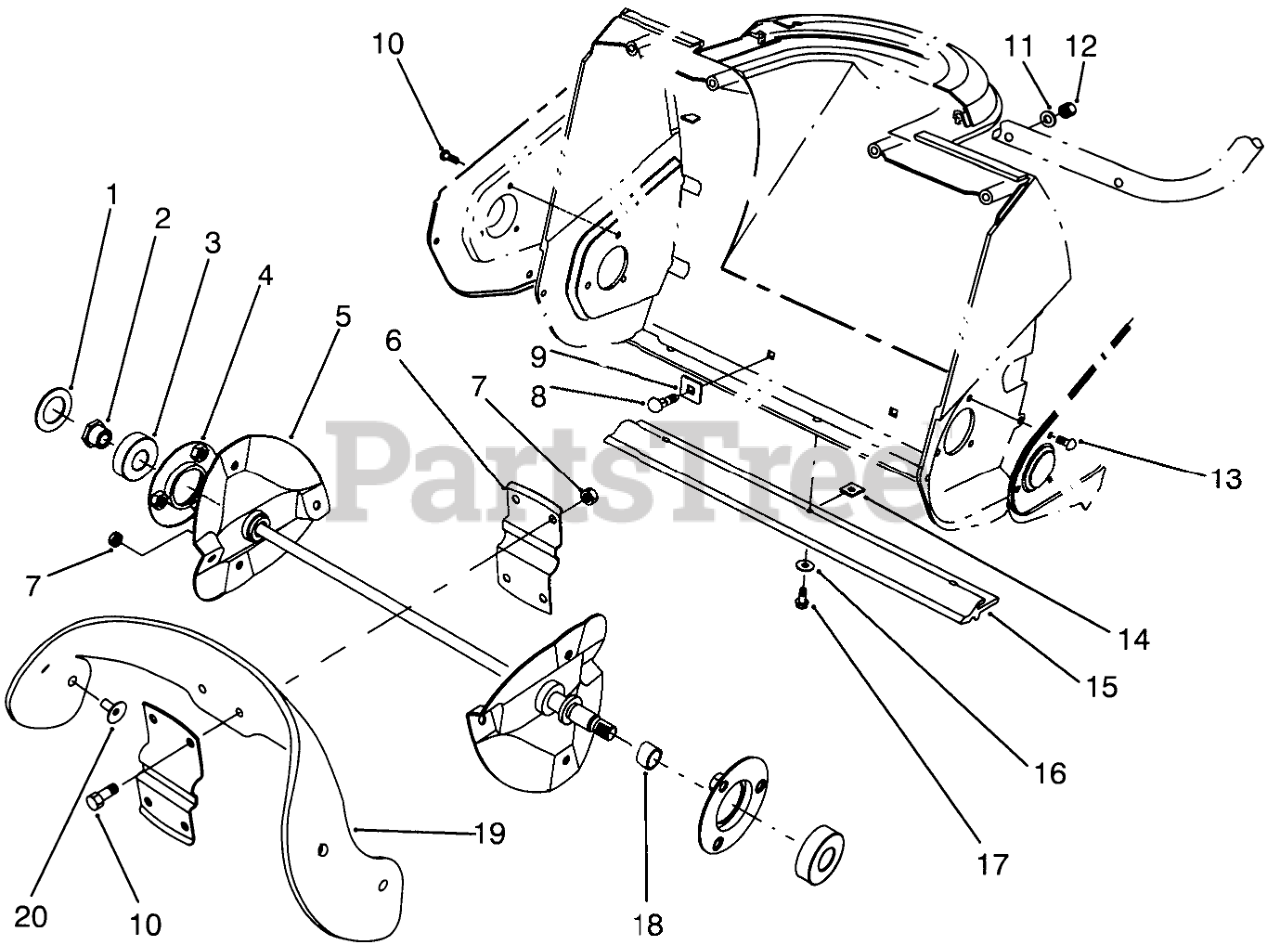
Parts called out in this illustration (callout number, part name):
1	WASHER-RUBBER
3	BEARING-BALL
4	FLANGE BEARING ASM
5	Rotor
6	Support-Rotor
7	NUT-LOCK, NI
8	SCREW-CARR
9	WASHER-SQUARE
10	SCREW-HHF
11	WASHER
12	NUT-LOCK, NI
13	SCREW-HH
14	NUT-CLIP, U
15	SCRAPER
16	WASHER-FLAT
17	SCREW-HWHTF
18	SPACER
19	BLADE-ROTOR
20	SCREW
